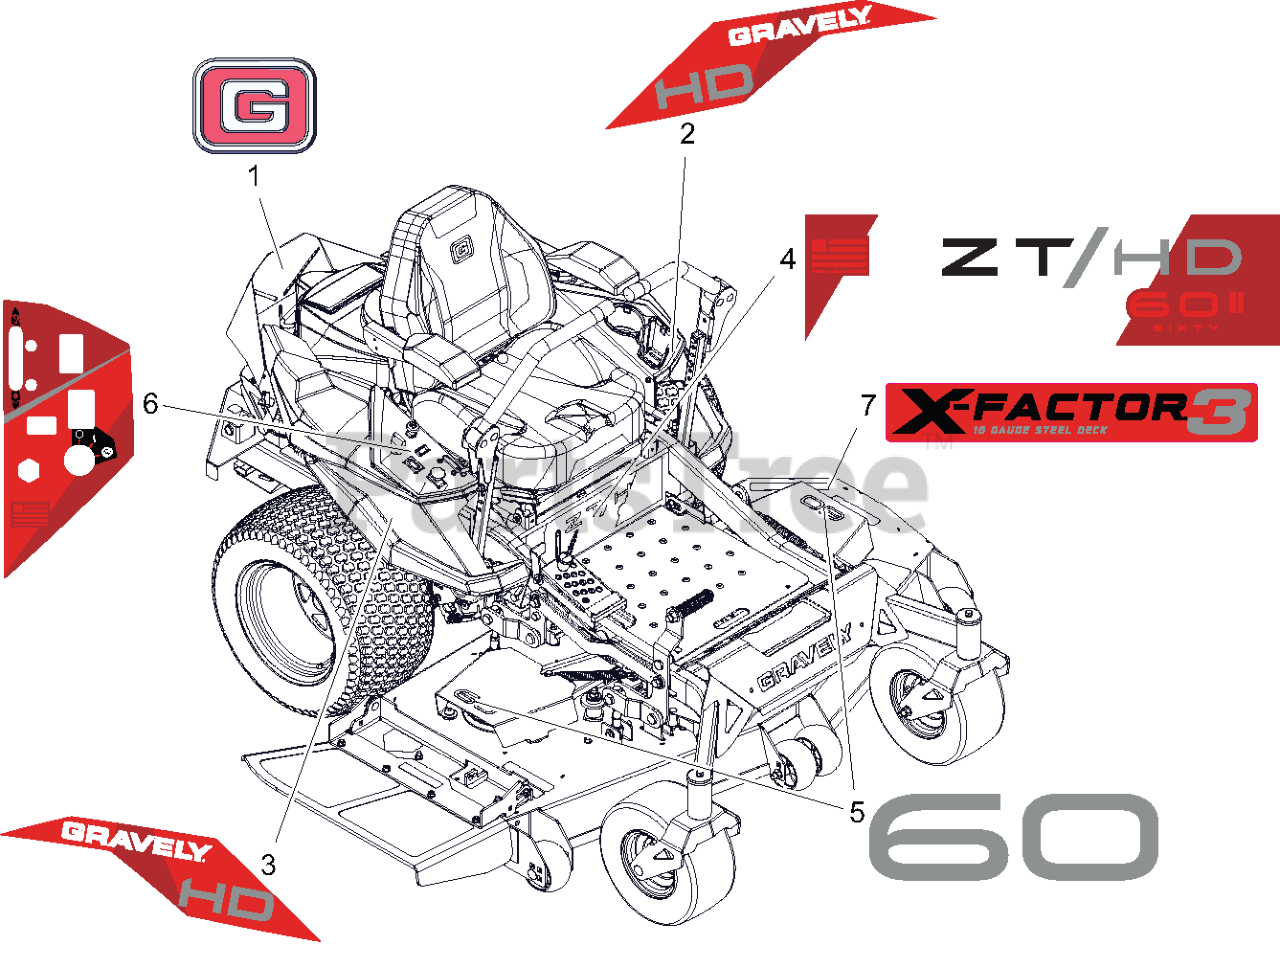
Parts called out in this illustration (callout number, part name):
1	DECAL, GRAVELY BRAND
2	DECAL, FENDER LH - HD
3	DECAL, FENDER RH - HD
4	DECAL, ZT/HD - 60
5	DECAL, DECK - 60
6	DECAL, CONTROL PANEL
7	DECAL, X-FACTOR 3
